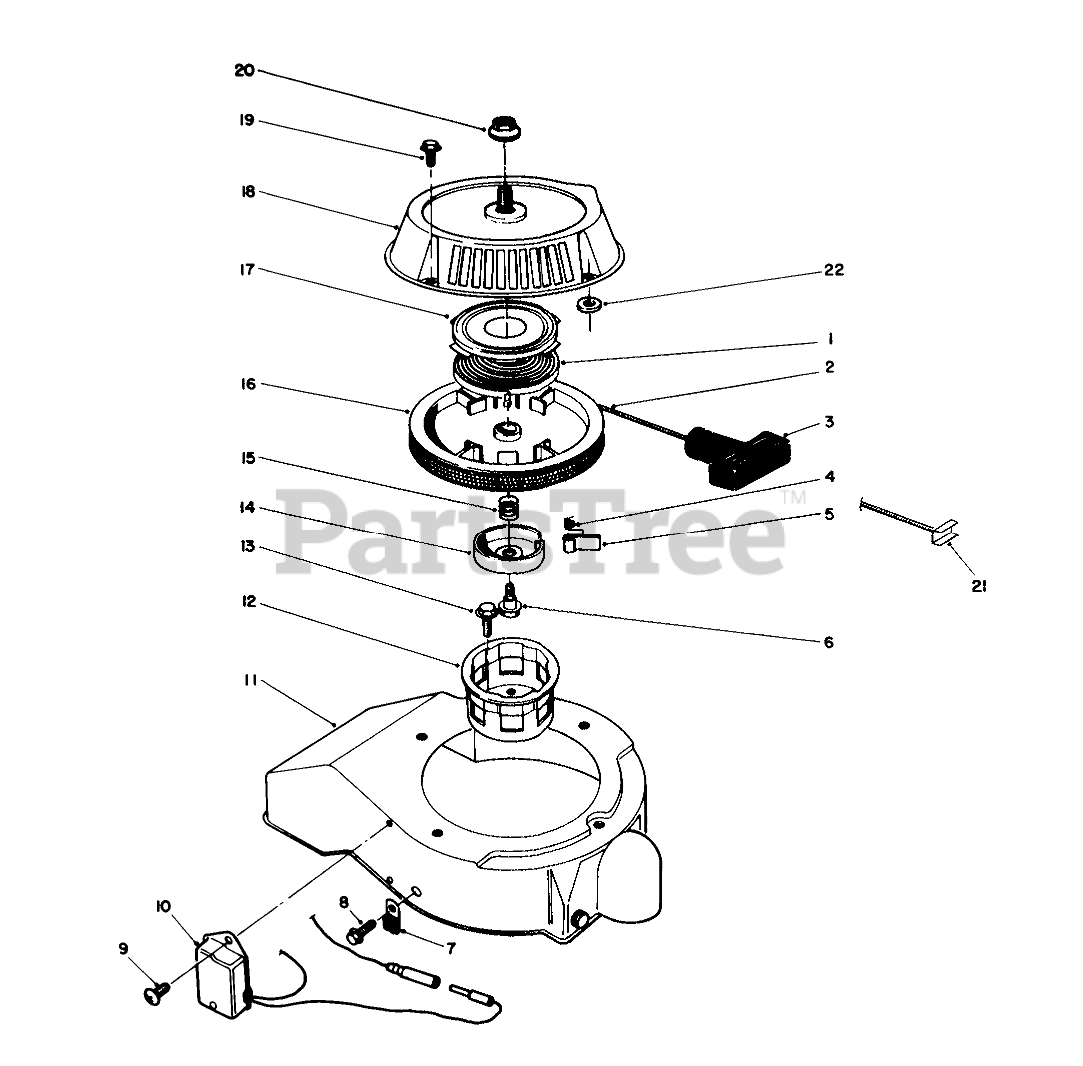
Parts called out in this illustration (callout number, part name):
1	Spring-Recoil
2	ROPE-STARTER
3	HANDLE-RECOIL
4	SPRING
7	CLAMP
9	SCREW
10	MODULE
11	SHROUD
12	CUP - STARTER
14	RETAINER
15	SPRING
17	Retainer-Recoil Spring
18	RECOIL CASE
19	MOUNTING SCREW
20	NUT (F/W & PPP)
21	Insert Handle
22	SPACER-PLATE, PIVOT
